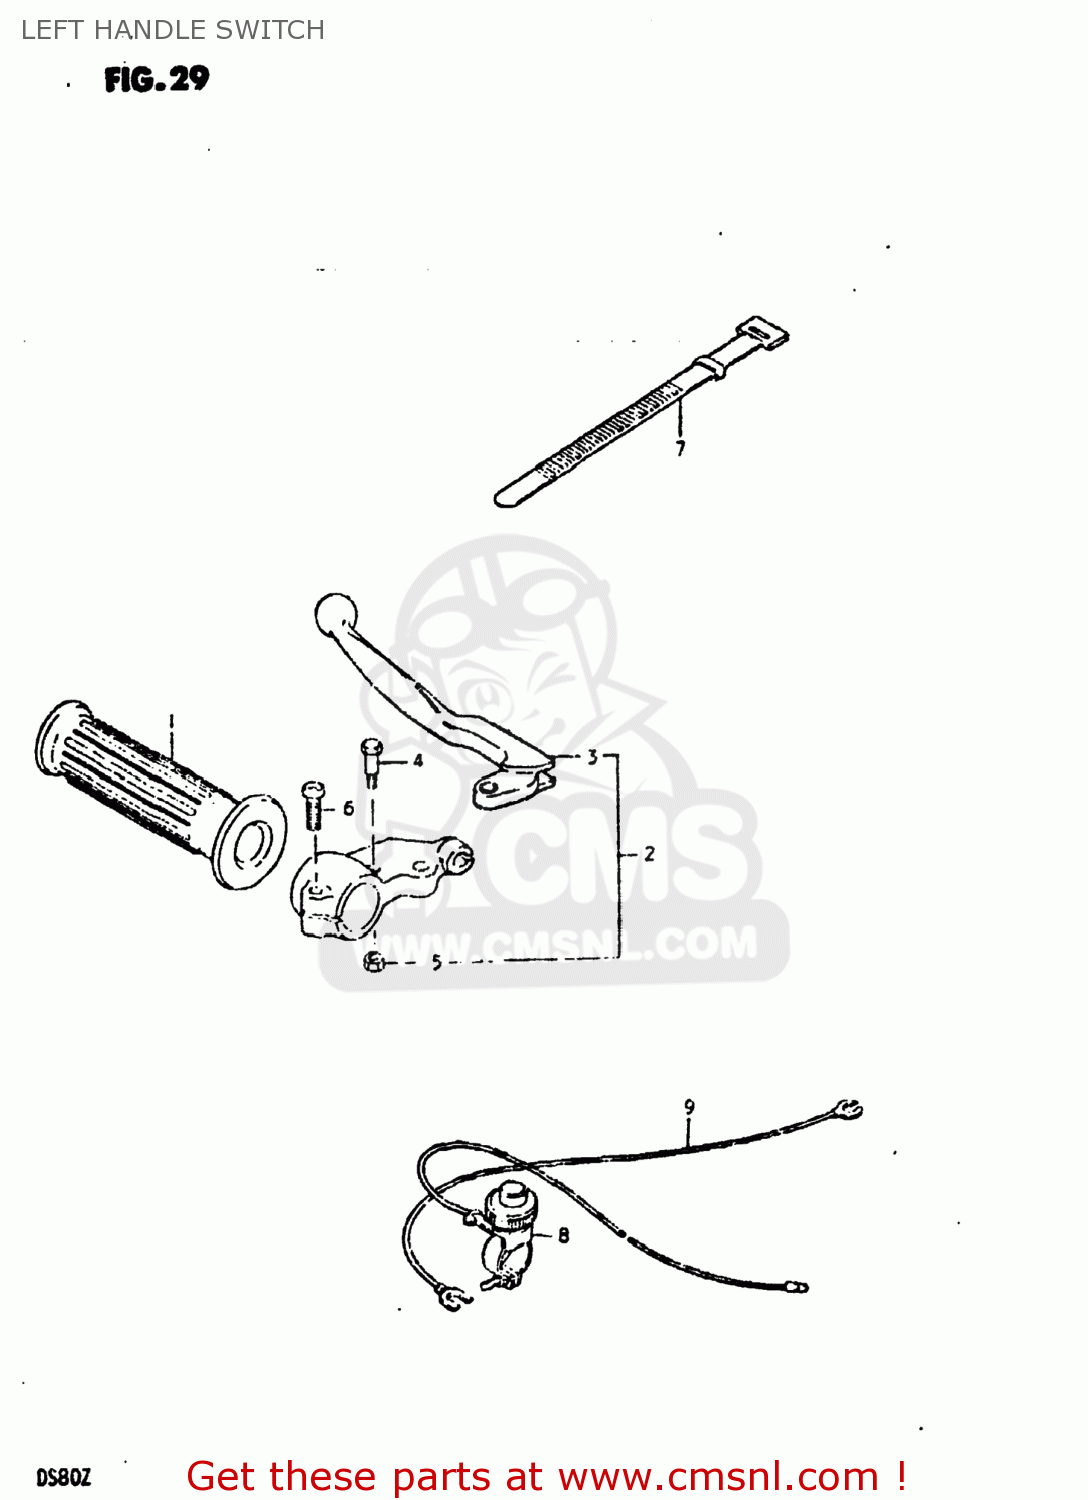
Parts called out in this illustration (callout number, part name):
1	GRIP,L
2	LEVER ASSY,CLUTCH
3	LEVER,CLUTCH
4	BOLT,LEVER
5	NUT
6	SCREW
7	CLAMP(L:120)
8	SWITCH ASSEMBLY
9	WIRE,ENGINE STOP EARTH
